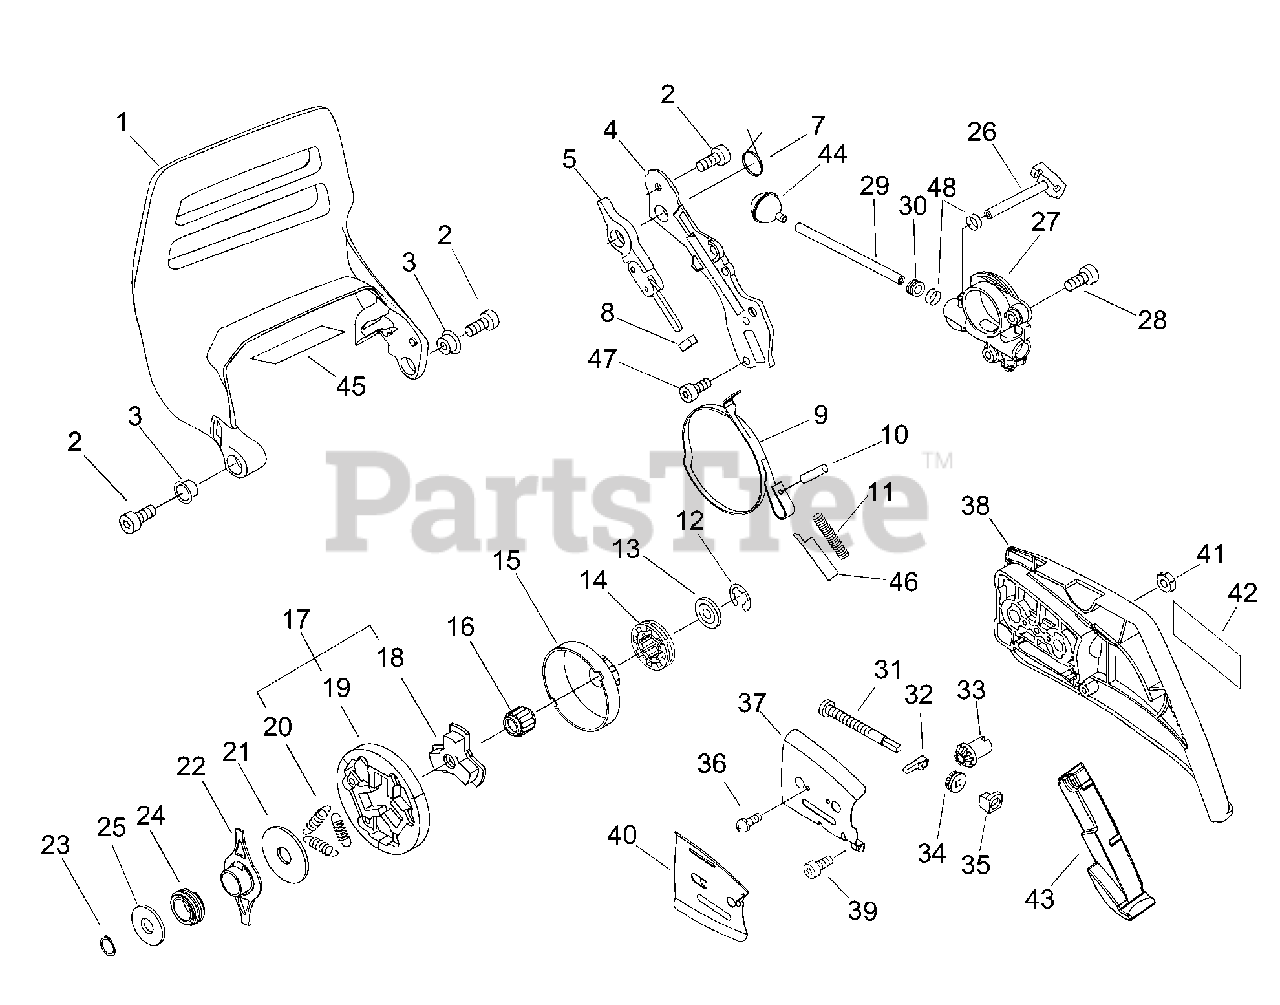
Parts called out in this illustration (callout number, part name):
1	BRAKE, CHAIN
2	BOLT, TORX 5×16
3	COLLAR 11.2×16.2×T0.6
4	COVER, BRAKE
5	CONNECTOR, BRAKE
7	SPRING, TORSION
9	BAND, BRAKE
10	PIN, SPRING 3x-9.8
11	SPRING, COMPRESSION Ø12×70.5
12	RING, SNAP Ø8 T: 1.2
13	WASHER 10×28.5×3.5(0.8)
14	SPROCKET, RIM 3/8"×7T
15	DRUM, CLUTCH
16	BEARING, NEEDLE 10
17	CLUTCH ASSY
18	HUB, CLUTCH
19	SHOE SET, CLUTCH (3PCS)
20	SPRING, TENSION
21	PLATE, CLUTCH
22	COLLAR 15×19×73
23	RING, RETAINING 15
24	GEAR, WORM
25	WASHER 15.5×22.5×0.5
26	PIPE, OIL
27	AUTO-OILER ASSY
28	BOLT, TORX 4×12
29	PIPE, FUEL 3×6×210 BLACK
30	GROMMET
31	SCREW, CHAIN TENSION
32	TENSIONER, CHAIN
33	GEAR, BEVEL
34	GEAR, BEVEL
35	COLLAR 8
36	SCREW 3×6
37	PLATE, GUIDE - OUTER
38	GUARD, SPROCKET
39	BOLT, TORX 4×12
40	PLATE, GUIDE - INNER
41	NUT 8
42	LABEL, ECHO
43	CUSHION, CLUTCH COVER
44	FILTER, OIL
45	SHIELD, HEAT 75×27×0.15
46	PLATE, SIDE
47	BOLT, TORX 4×12
48	CLIP Ø6
